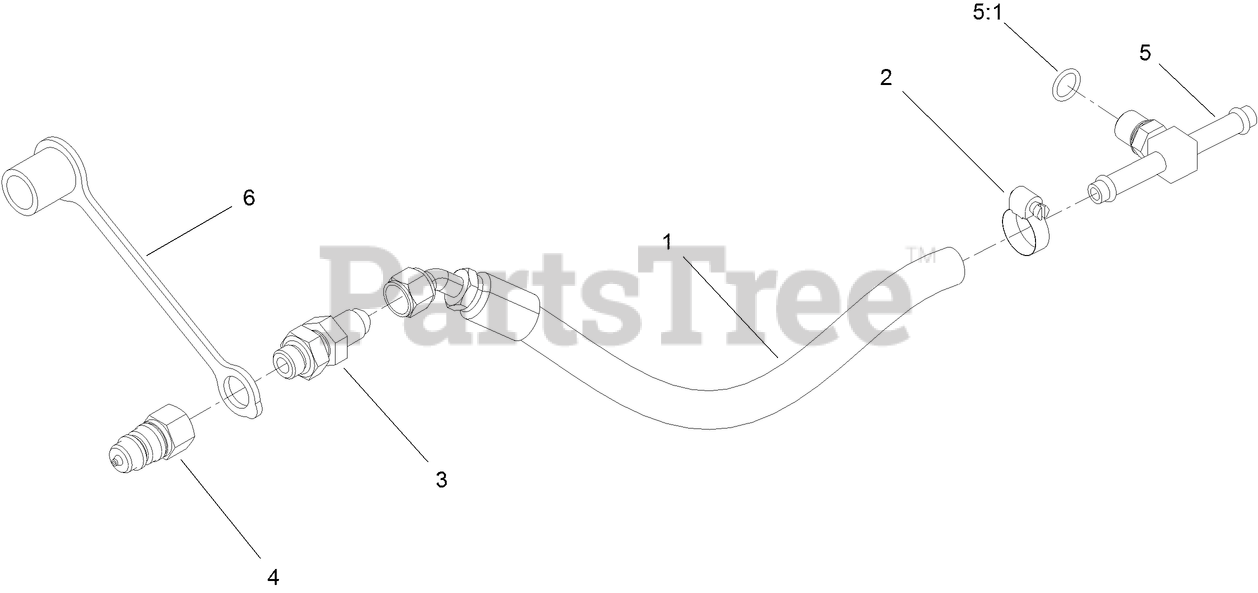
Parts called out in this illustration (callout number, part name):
1	HOSE ASM
2	CLAMP-HOSE
3	FITTING, BULKHEAD
4	NIPPLE-DISCONNECT, QUICK
5	FITTING-TEE
5:1	O-RING
6	CAP-DUST
